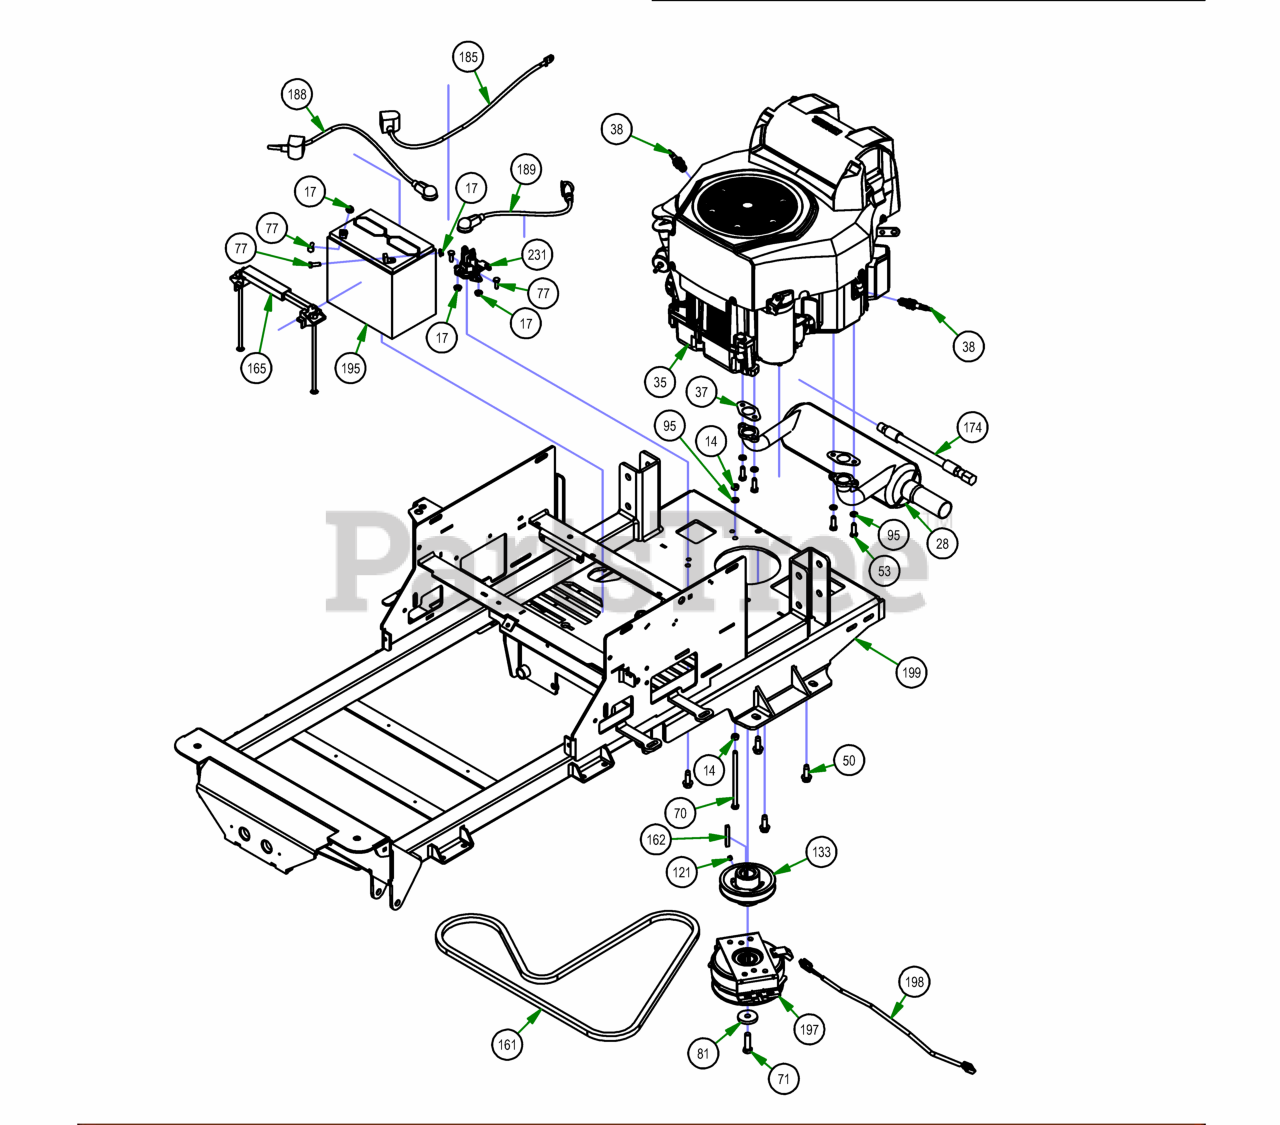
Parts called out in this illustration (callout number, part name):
14	5/16-18 HEX NUT ZINC
17	1/4-20 HEX SERRATED FLANGE NUT HARD/ZINC
28	Kohler Muffler
35	Kohler-2014 CZT/Outlaw 747cc
37	Exhaust Gasket
38	Spark Plug
50	3/8-16 X 1-1/8 HEX WASHER UNSLOT SERRATED (TRI-LOB) TRS ZINC YELLOW
53	5/16-18 X 1 HEX CAP SCREW (GR.5) ZINC
70	5/16-18 X 5-1/2 HEX CAP SCREW (GR.5) ZINC
71	7/16-20 X 1-1/2 HEX CAP SCREW (GR.8) ZINC YELLOW
77	1/4-20 X 3/4 HEX CAP SCREW (GR.5) ZINC
81	CLUTCH WASHER
95	5/16 SPLIT LOCKWASHER ZINC
121	5/16-24 X 1/4 SOCKET SET SCREW (CUP PT) PLAIN
133	4 3/4 Motor Pulley
161	75.8" Pump Belt
162	1/4 X 2 SQ MACHINERY KEY 1018 STL PLAIN
165	Hold Down Assembly
174	Oil drain Hose
185	24 inch Black Cable – MZ/ZT
188	24" Red Battery Cable
189	12" Red Battery Cable
195	SP-35 Battery
198	Clutch Pigtail
199	2021 Maverick Frame - Painted
213	Patent Decal
